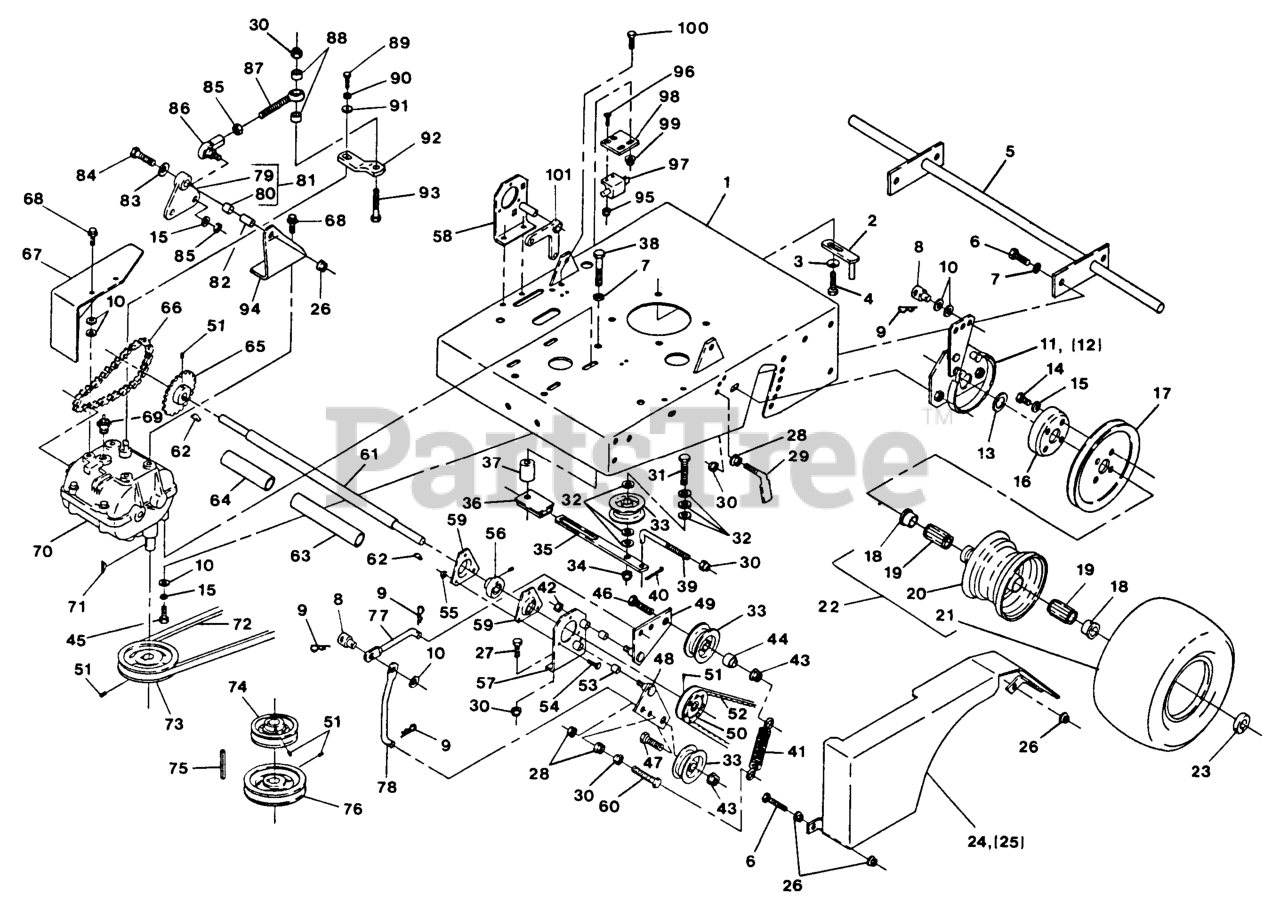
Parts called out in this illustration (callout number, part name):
2	GUIDE - BELT, 32
3	WASHER-SPRING
8	SWIVEL,SHORT ADJUSTING
9	PIN-COTTER
15	WASHER-LOCK
17	SHEAVE,SPLIT STEEL 9 B
19	BEARING,ROLLER
23	COLLAR,LOCKING 7/8
33	PULLEY,IDLER
39	TIGHTENING ARM
41	SPRING-EXTENSION
42	NUTTORQUE ZKPLT
48	ARM - IDLER
49	ARM - IDLER
51	SCREW-SET
52	BELT,COG
61	JACKSHAFT
66	CHAIN,DRIVE
69	SWITCH-START, NEUTRAL
72	BELT,TRANSMISSION
75	KEY,MACH 1/4X1/4X2-5/8
76	PULLEY,CAST IRON
78	LINKAGE,LOWER CALIPER RH
80	SLEEVE-BEARING
86	BALLJOINT
88	SPACER-PLATED
90	WASHER-LOCK
92	LEVER,TRANSMISSION
97	SWITCH-OPEN, NORMALLY
98	BRACKET,SAFETY SWITCH
101	BELLCRANK
